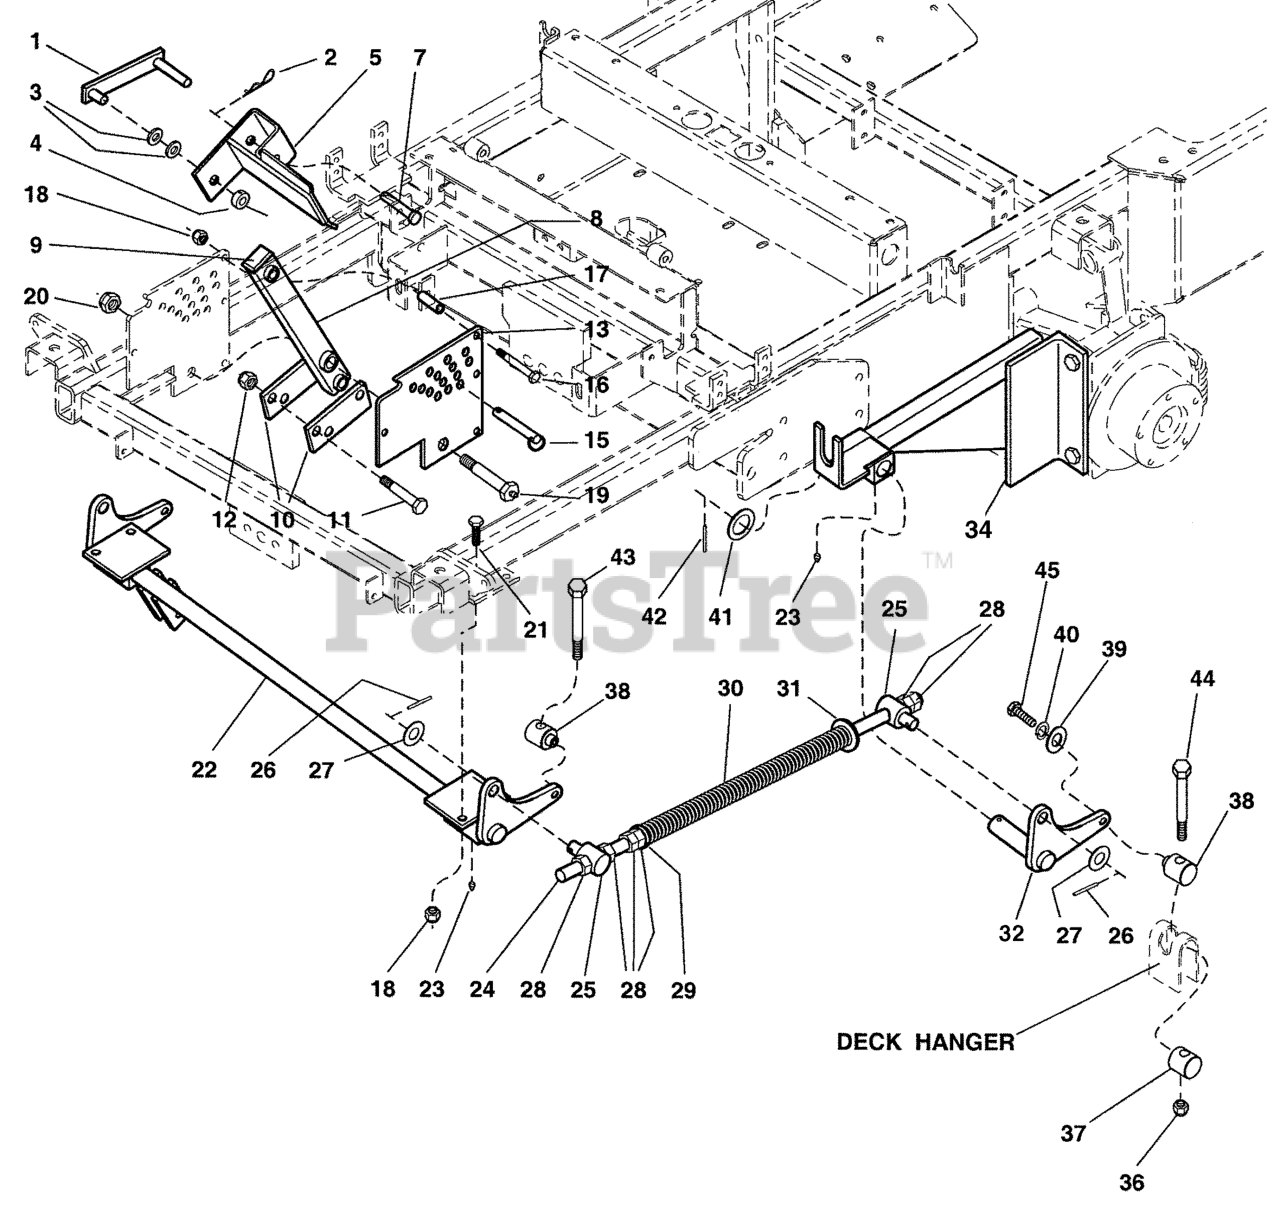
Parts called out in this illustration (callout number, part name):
1	DECK LIFT LOCK
2	HAIRPIN CLIP
3	WASHER, 1/2 SAE
4	COLLAR, 1/2 Set
5	WELD, DECK LIFT PEDAL
7	PIN, Clevis, 1/2 x 2-1/2
8	ARM, Deck Lift Pivot
10	LINK, Deck Lift
11	BOLT, 1/2-20 x 3
12	NUT, Hex, Nylon Lock, 1/2-20
13	DECK HEIGHT PLATE
15	PIN, 1/2 x 3
16	BOLT, 3/8-16 X 2-3/4" GD5 CZ
17	SPACER, Lift Plate
18	NUT, 3/8-16 HEX NYLON LOCK
19	LIFT PIVOT BOLT
20	NUT, Hex Jam, Nylon Lock, 5/8-11
21	BOLT, 3/8-16 X 1-1/4" GD5 CZ
22	DECK LIFT SHAFT & MOUNT ASSEMBLY
23	CREASE FITTING
24	SPRING ROD
25	SPRING ROD PIVOT
26	PIN, Spring, 3/16 x 1-1/4
27	WASHER, 5/8
28	NUT, Hex, 5/8-11
29	SPACER
30	SPRING, Deck Lift
31	WASHER, USS, 5/8
32	DECK LIFT PIVOT-LH
34	REAR DECK LIFT FRAME-LH
36	NUT, 1/2-13 HEX NYLON LOCK
37	BUSHING, DECK PIVOT
38	LIFT, BOLT PIVOT
39	WASHER, Fender, 5/16
40	WASHER, 5/16 LOCK CZ
42	PIN, Roll, 3/16 x 1-1/2
43	BOLT, 1/2-20 x 8-1/2
44	BOLT, 1/2-20 x 6-1/2
45	BOLT, 5/16-24 x 3/4
